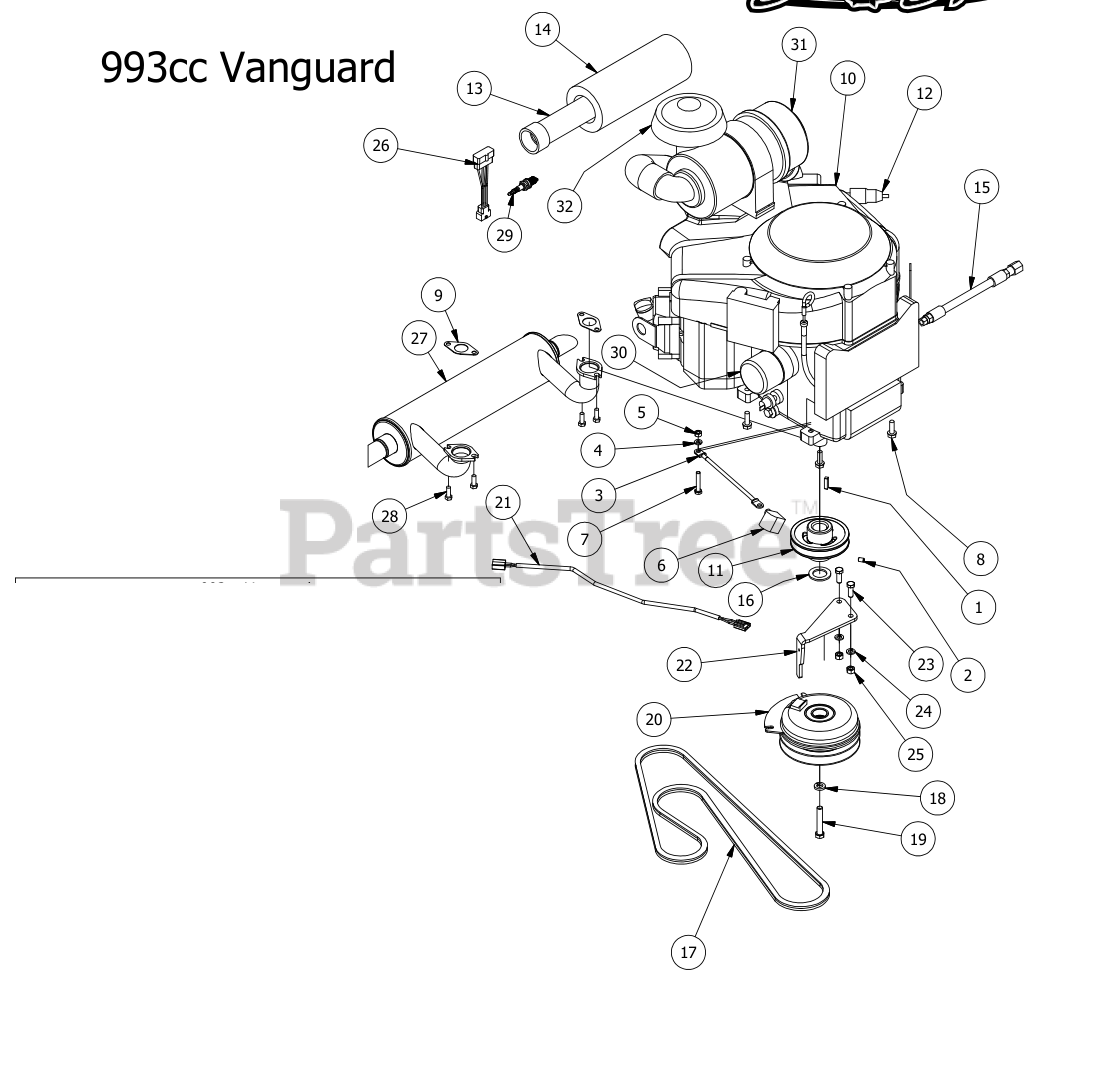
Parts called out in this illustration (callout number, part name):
1	1/4" x 1" Key
2	5/16 Set Screw
3	Ground Cable
4	5/16" Lock Washer
6	Black Boot For Ground Cable
7	5/16" x 1 3/4" Hex Bolt
8	3/8 x 1 1/8 bolt
9	Exhaust Gasket for 23 Vanguard
10	993cc Briggs Vanguard Engine
11	4 3/4 Motor Pulley
12	Universal Inline Fuel Filter
13	Canister Air Filter- Inner
14	Canister Air Filter- Outer
15	14 mm Oil drain Hose 993cc Vanguard
16	1 1/8" Flat Spacer
18	7/16" Lock Washer
19	7/16" x 2 1/2" Hex Bolt
20	Clutch Assembly
21	Clutch Pigtail
22	PTO Engager Holder
23	3/8" x 1" Hex Bolt
24	3/8" Lock Washer
25	3/8" Hex Nut
26	Harness Adaptor - 933cc Vanguard
27	2015 Exhaust-36hp Vanguard
28	Torx Bolt-Exhaust-23hp Vanguard
29	Spark Plug
30	Briggs Oil Filter
31	Complete Canister
32	Rain Cap Fits all Canisters
